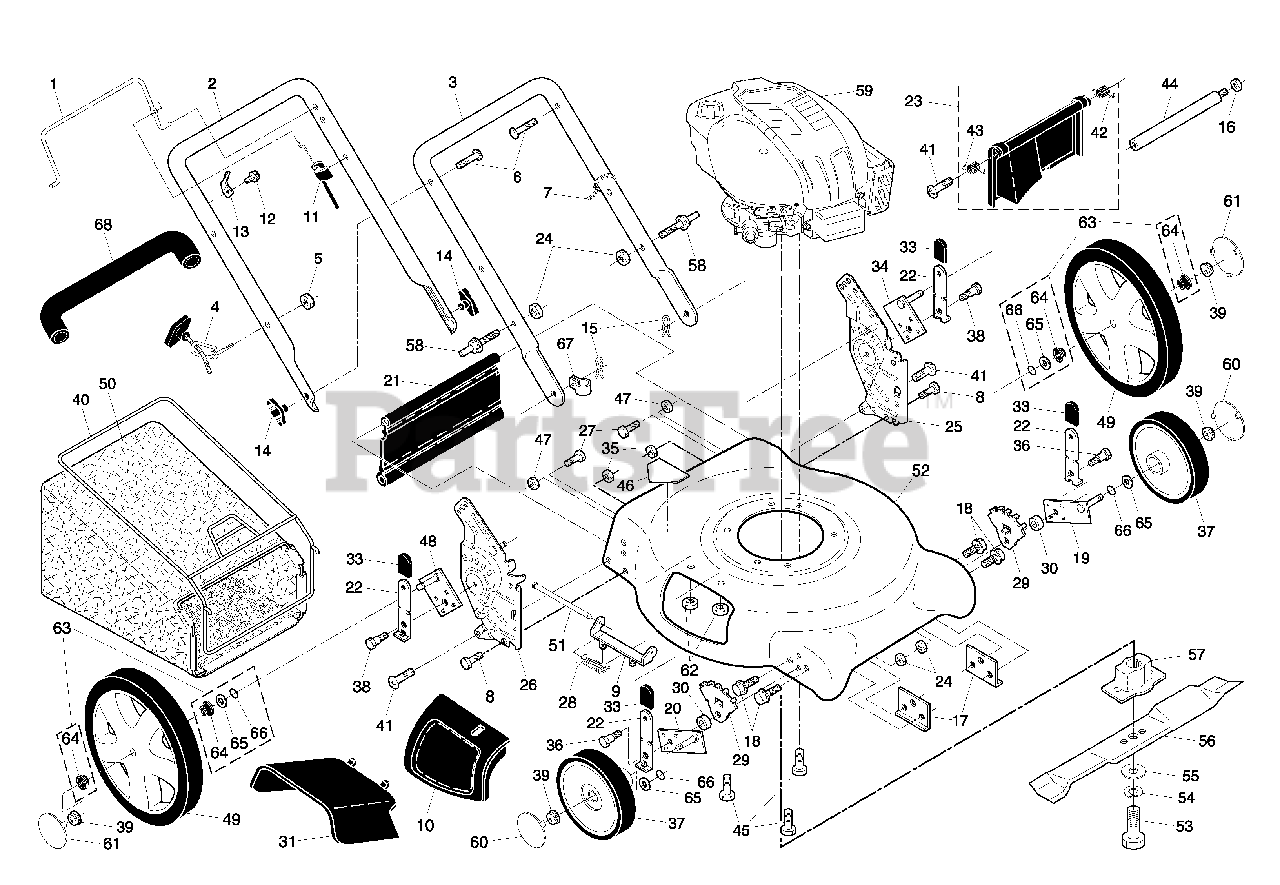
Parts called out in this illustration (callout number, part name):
1	Control Bar
2	Upper Handle
3	Lower Handle
4	Rope Guide
5	Locknut, Hex 1/4-20
6	Handle Bolt
7	Wire Tie
8	Hex Bolt 5/16-18 x 3/4
9	Hinge Bracket Assembly
10	Mulcher Door
11	Engine Zone Control Cable
12	Hex Washer Head Screw #10-24 x 1/2
13	Up-Stop Bracket
14	Handle Knob
15	Hairpin Cotter
16	Nut, Hex, Flangelock 1/4-20
17	Support Bracket
19	Axle Arm Assembly, Front, LH
20	Axle Arm Assembly, Front, RH
21	Rear Skirt
22	Selector Spring
23	Kit, Rear Door
24	Locknut, Hex 5/16-18
25	Handle Bracket Assembly, LH
26	Handle Bracket Assembly, RH
27	Screw 1/4-20 x 3/8
28	Spring, Torsion
29	Wheel Adjusting Bracket, Front
31	Discharge Deflector
33	Selector Knob
34	Axle Arm Assembly, Rear, LH
35	Locknut, Hex 5/16-18
36	Shoulder Bolt 5/16-18
37	Wheel & Tire Assembly, Front 8 x 2
38	Shoulder Bolt
39	Nut, Hex, Flangelock
40	Frame, Grassbag
41	Hinge Screw
42	Spring, Rear Door, LH
43	Spring, Rear Door, RH
44	Rod, Rear Door
45	Hex Head Thread Rolling Screw 3/8-16 x 1
46	Danger Decal
48	Axle Arm Assembly, Rear, RH
49	Wheel & Tire Assembly, Rear 14 x 2
50	Grassbag
52	Kit, Lawn Mower Housing Assembly
53	Hex Head Screw 3/8-24 x 1-3/8 Grade 8
54	Helical Lockwasher
55	Hardened Washer
57	Blade Adapter
58	Adjustment Bolt
59	Engine, Briggs & Stratton, Model Number 12H602 (Order parts from engine manufacturer)
60	Hubcap, Front Wheel, 8"
61	Hubcap, Rear Wheel, 3"
62	Nut, Hex, Nylock 1/4-20
63	Kit, Bushing, High Wheel
64	Bushing, Nylon, Black
65	Washer, Flat
66	O-Ring
67	Clip, Cable
68	Grip, Foam
